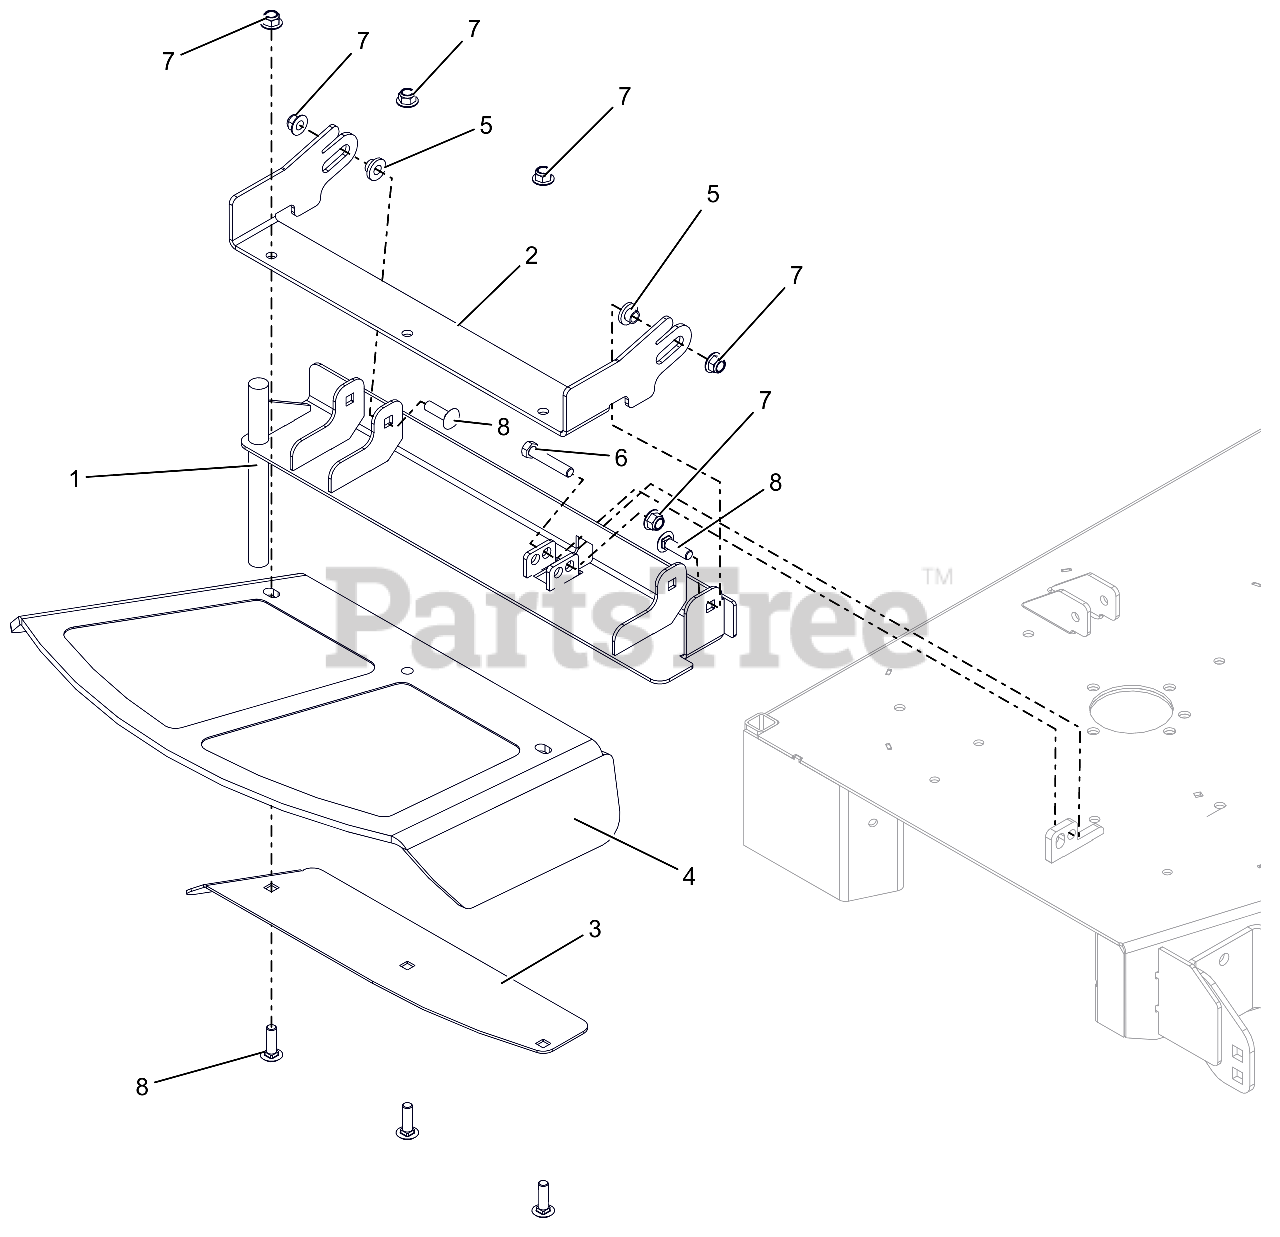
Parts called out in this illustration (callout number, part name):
1	48-60 DISCH CHT MTG WMT W/SAFE
2	48-60" CHUTE MTG BRKT - RED
3	48-60 DISCH CHUTE CLMP PLT-RED
4	CHUTE,48-60" FRMD RUBBER DISCH
5	BSHG-FLG .385X.500X.875X.406
6	BLT,HEX .38-16X2.00 G5 ZCC
7	NUT,NYL-FLG .38-16 GF ZCC
8	BLT,RHSSN .38-16X1.25 G5 ZCC
